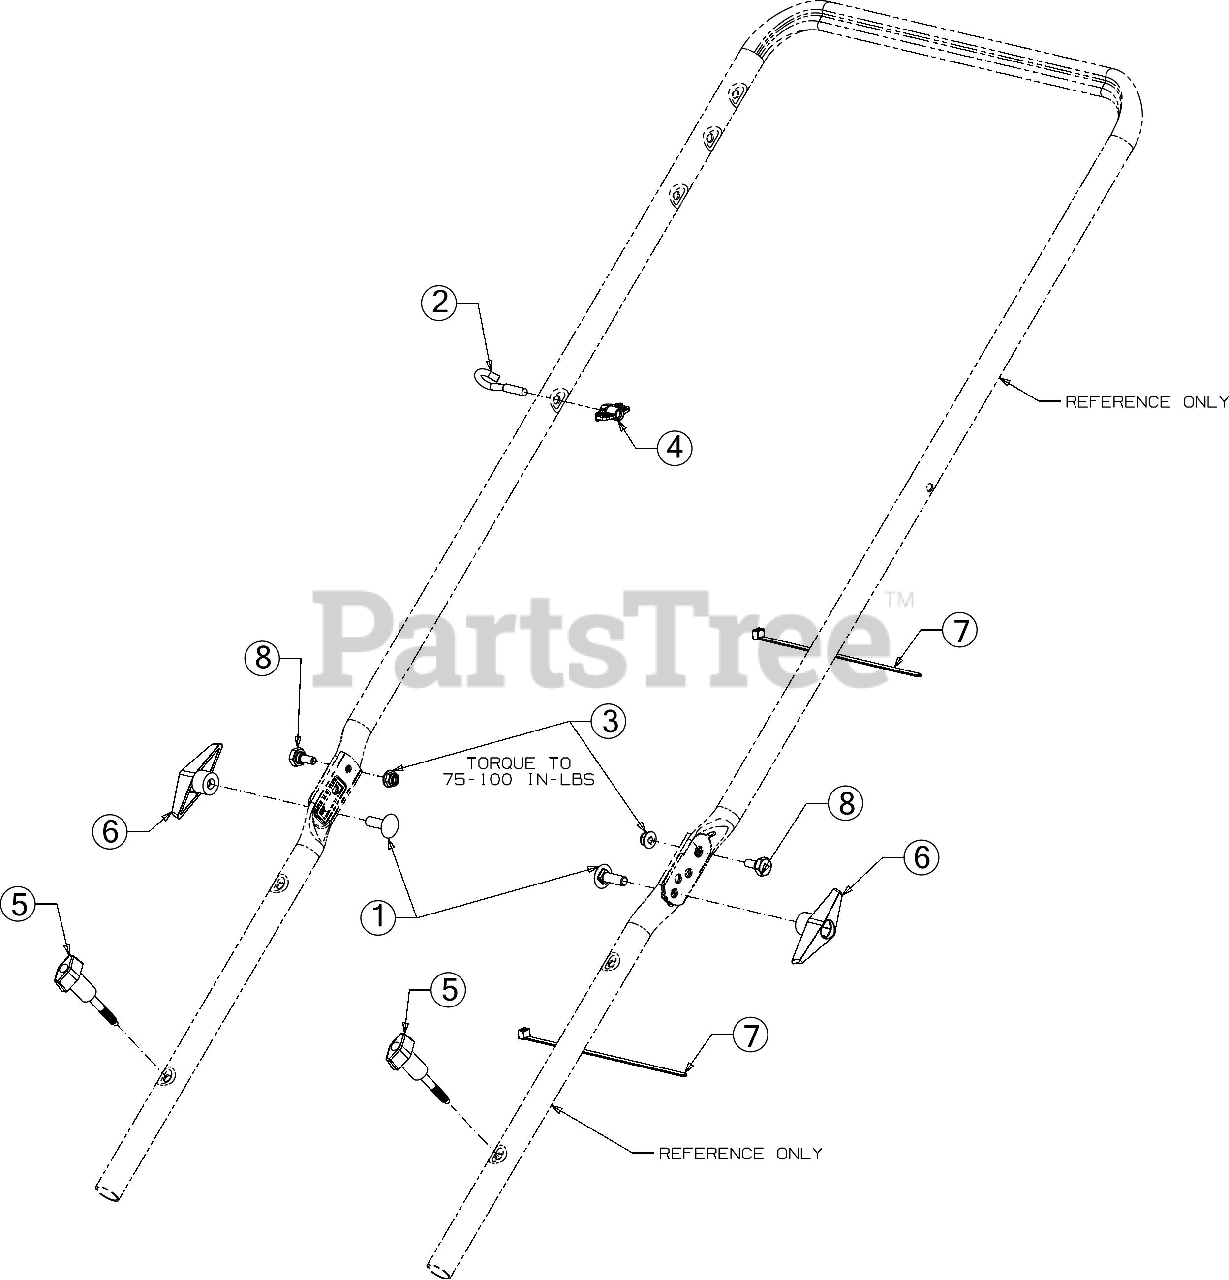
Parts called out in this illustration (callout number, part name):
1	SCREW 5/16-18 x 1.00 GR5
2	EYEBOLT 1/4-20
3	FLANGE LOCK NUT
4	HANDLE KNOB
5	WING KNOB 1/4-20
6	KNOB ASSEMBLY-W/NUT
7	7" CABLE TIE
8	SHOULDER SCREW
